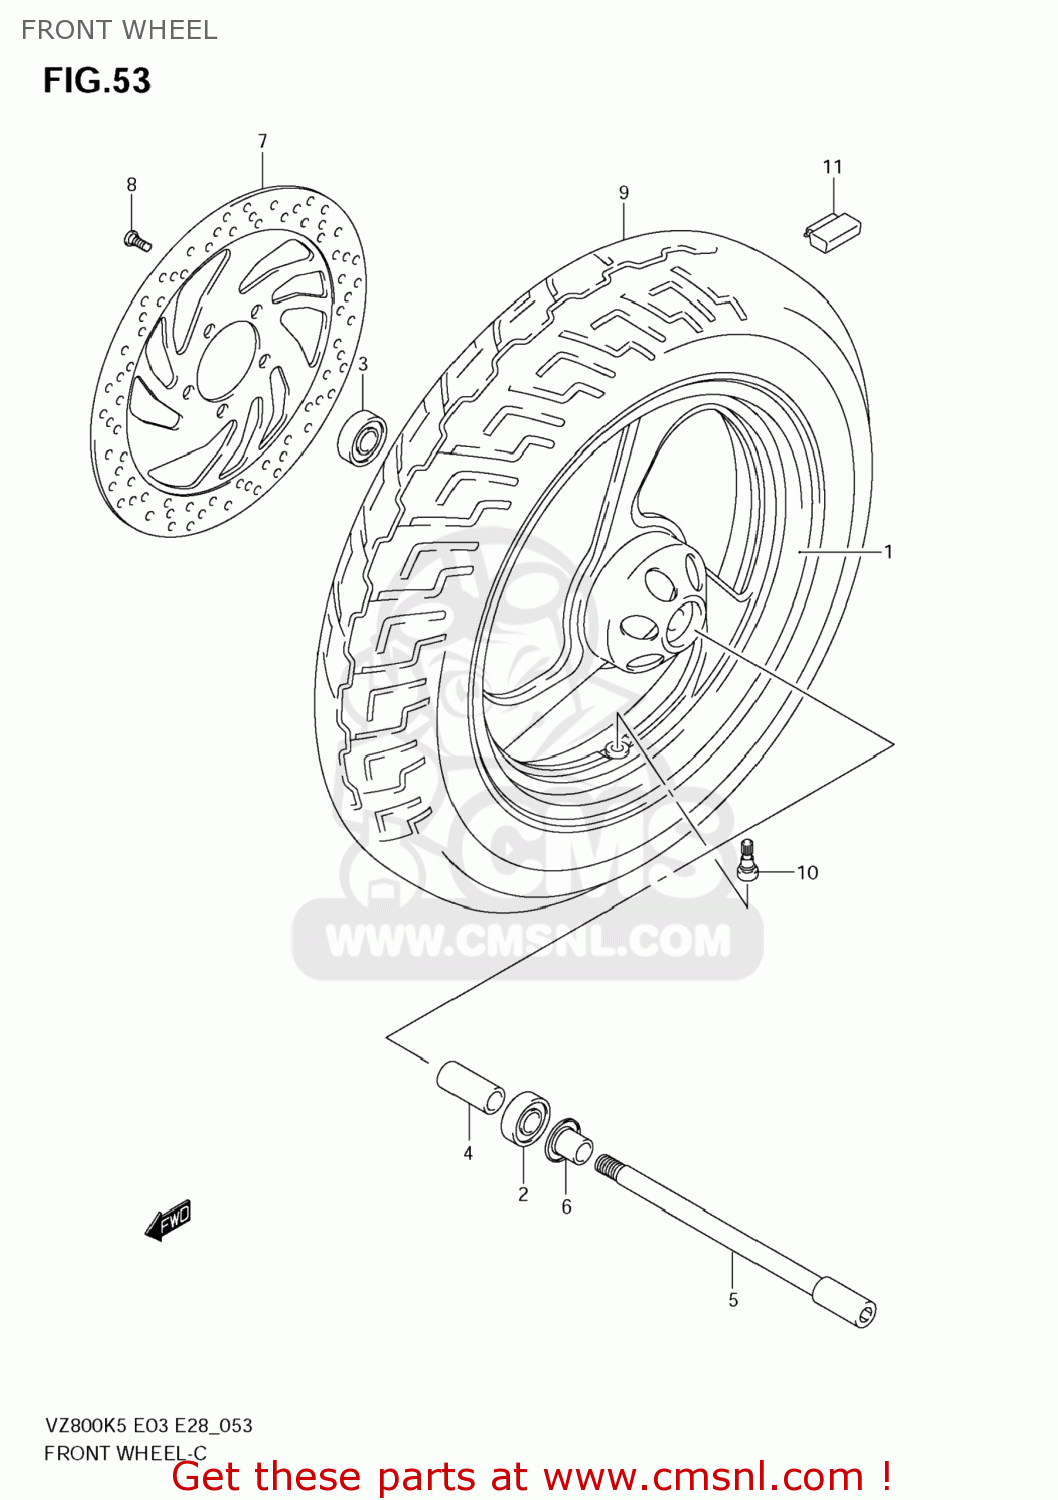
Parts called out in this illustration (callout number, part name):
1	WHEEL,FR(16M/CXMT3.00)
2	BEARING
3	BEARING
4	SPACER(17.5X25X113)
5	AXLE,FR
6	SPACER,FR AXLE,R
7	DISC,FR BRAKE
8	BOLT(8X21)
9	TIRE,FR(130/90-16M/C 67H)
10	VALVE ASSY,WHEEL RIM(TR412)
11	BALANCER,WHEEL(10G)
